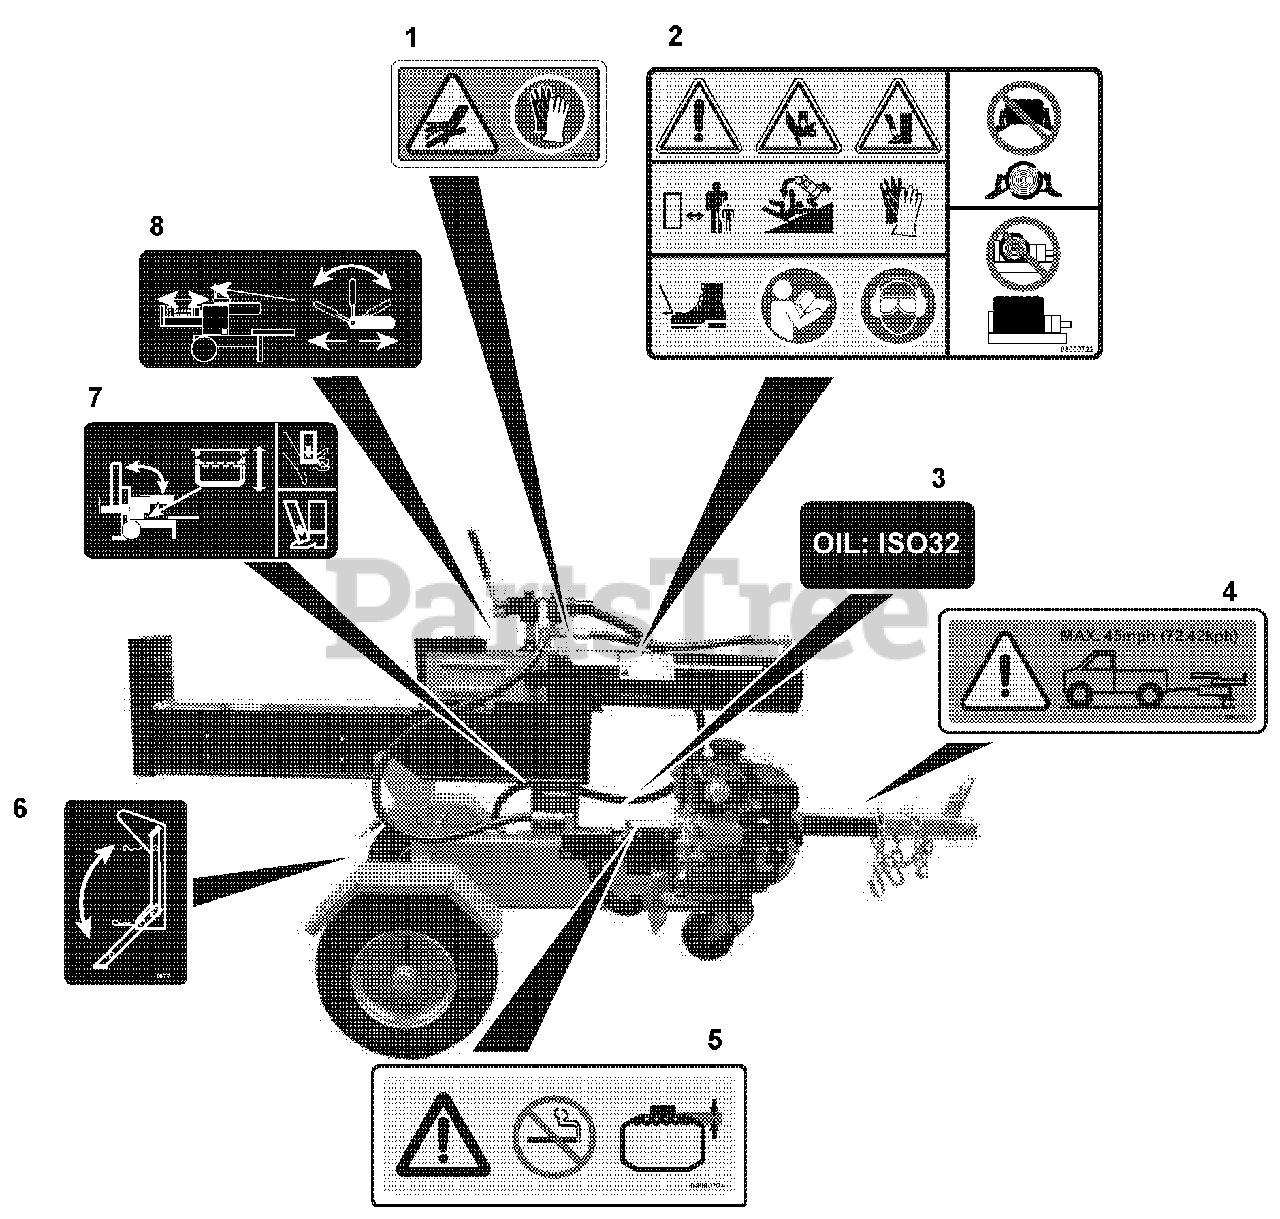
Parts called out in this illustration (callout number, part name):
1	DECAL,HYD WARNING
2	DECAL,DANGER LOG SPLITTER
3	DECAL, LOG SPLITTER-HYD OIL
4	DECAL,TOWING
5	DECAL,FUEL WARNING
6	DECAL, LOG SPLITTER-REAR STAND
7	DECAL, LOG SPLITTER-TILT OP
8	DECAL, LOG SPLITTER-RAM OP
